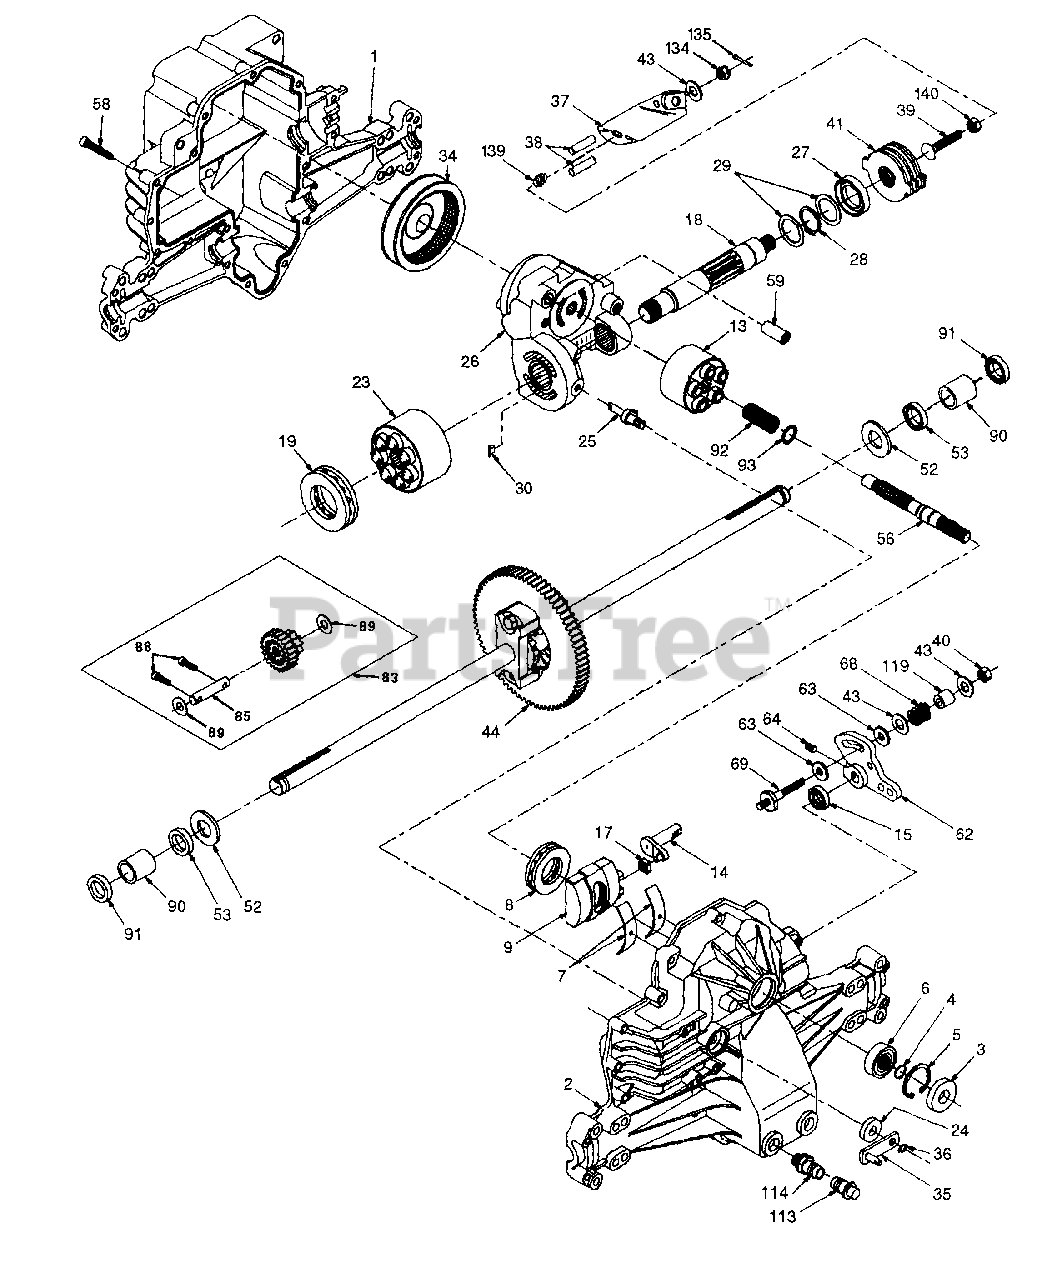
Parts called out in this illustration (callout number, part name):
1	Housing, Lower
2	Assembly, Upper Housing
4	Ring, Wire Retaining
5	Ring, Retaining
6	Bearing, Shaft Ball
7	Bearing, Cradle
8	Bearing, Thrust 30 x 52 x 13
9	Swashplate, Variable
13	Block, Cylinder Assembly
14	Arm, Trunnion
17	Guide, Slot
18	Shaft, Motor
19	Bearing, Thrust 42 x 68 x 16
23	Block, Cylinder Assembly
24	Seal, Lip 10 x 25 x 7
25	Actuator, Bypass
26	Center Section Assembly Kit
27	Seal, Lip 26 x 42 x 8
28	Ring, Retaining
29	Washer 26 x 35 x 1
34	Oil Filter Element
35	Arm, Bypass
36	Ring, Retaining
37	Arm, Actuating
38	Pin, Actuating
39	Bolt 5/16-24 x 1-3/4
40	Locknut, Hex 5/16-24 UNJC
41	Brake Rotor/Stator Kit
43	Washer 7/16 x 7/8 x .060
44	Differential Assembly
52	Washer 3/4 x 1.5 x .13
53	Seal .75 x 1.25 x .250
56	Shaft, Input
58	Bolt 1/4-20 x 1.38
59	Pin .SOD x.43 ID x.750
62	Arm, Control
63	Puck, Dampener
69	Stud 5/16-24
83	Jackshaft Assembly
88	Screw, Cap
89	Washer 7/16 x 1 x 1/2
90	Sleeve Bearing
91	Seal, Wiper
92	Spring, Block
93	Washer, Block Thrust
113	Cap, Vent Assembly
114	Fitting, 0-Ring Assembly
119	Spacer
134	Nut, Castle 5/16-24
135	Pin, Cotter
139	Spring, Compression
140	Nut, Hex 5/16-24
